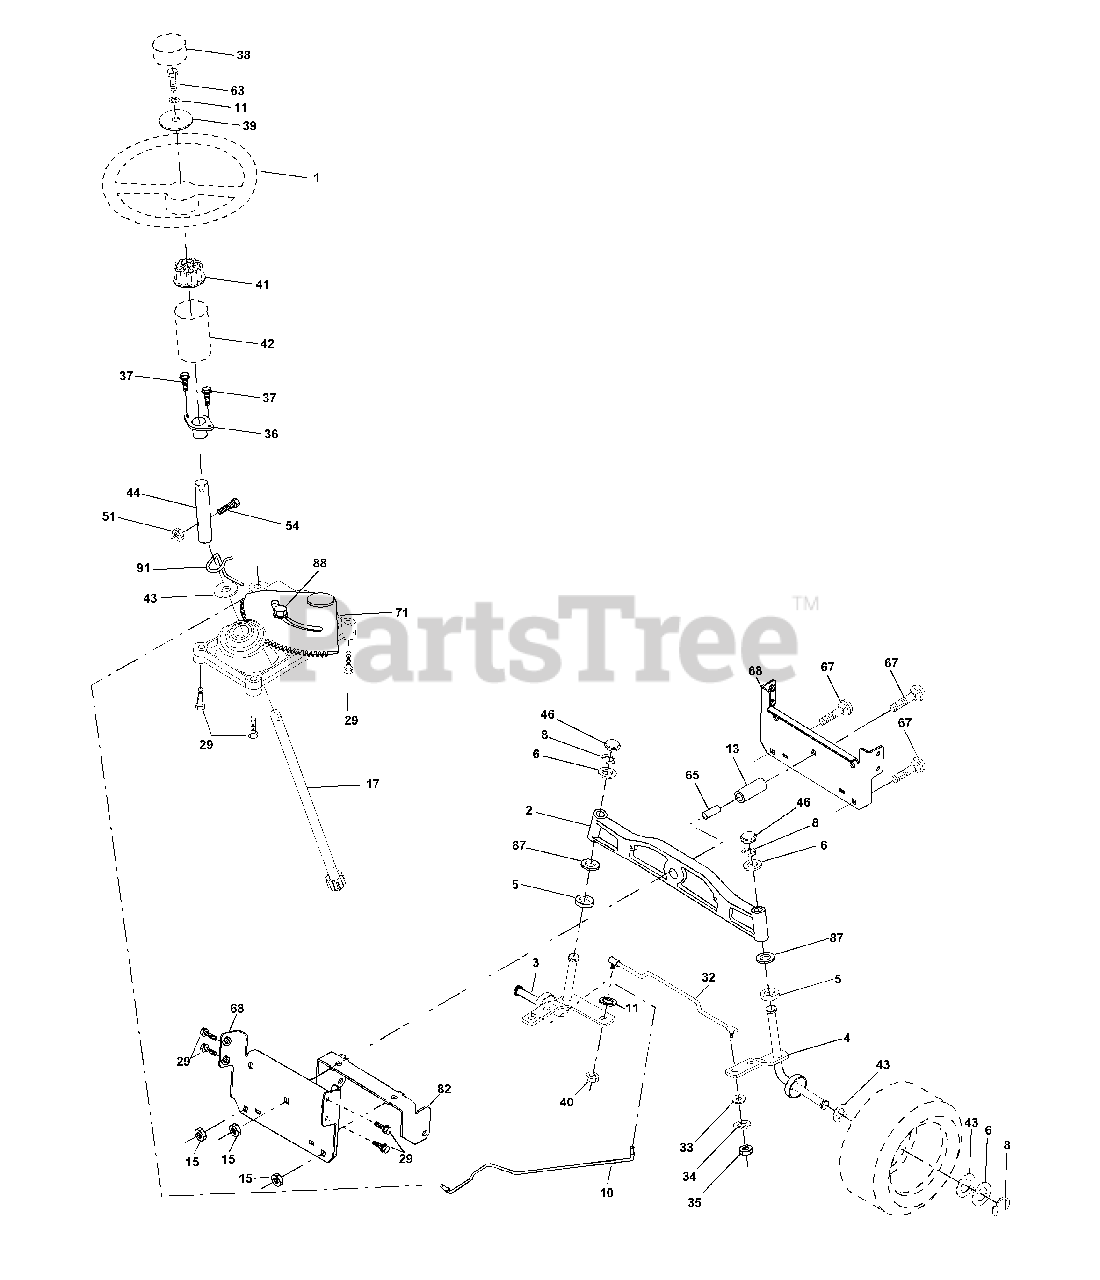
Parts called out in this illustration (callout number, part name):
1	Wheel Steering
2	Axle Asm Cast Iron LT
3	Spindle Asm LH
4	Spindle Asm RH
5	Bearing Race Thrust Harden
6	Washer 25/32 X 1-5/8 X 16 Ga
8	Ring Klip #t5304-75
10	Link Drag
11	Washer Lock Hvy Hlcl Spr 3/8
13	Spacer Brg Axle Front
15	Nut Hex Flange Lock
17	Shaft Asm Strg
29	Screw 3/8-16 x .75
32	Rod Tie
33	Washer 11/32 x 3/4 x 16 Ga
34	Washer Lock Hvy Hlcl Spr 5/16
35	Crownlock Nut 5/16-24 Unf
36	Bushing Strg
37	Screw
38	Insert Cap Strg Wh
39	Washer 13/32 X 1-1/2 X 11 Ga
40	Lock nut
41	Adaptor Wheel Strg
42	Boot Steering Dash
43	Washer 25/32 X 1 1/4 X 16 Ga
44	Extension Steering Shaft LR/LT
46	Cap Spindle Fr Top Blk
51	Nut Lock Hex w/Ins 5/16-18
54	Bolt Fin Hex 5/16-18 Unc x 1-1/4
63	Bolt Fin Hex 3/8-16unc x 1 Gr. 5
65	Spacer Brace Axle
67	Bolt Rdhd Sq 3/8-16 Unc x 2-3/4
68	Axle, Brace
71	Steering Asm.
82	Bracket Susp Chassis Front
87	Washer Flat .781 x 1 1/2 x .14
88	Bolt Shoulder 7/16-20
91	Clip Steering
